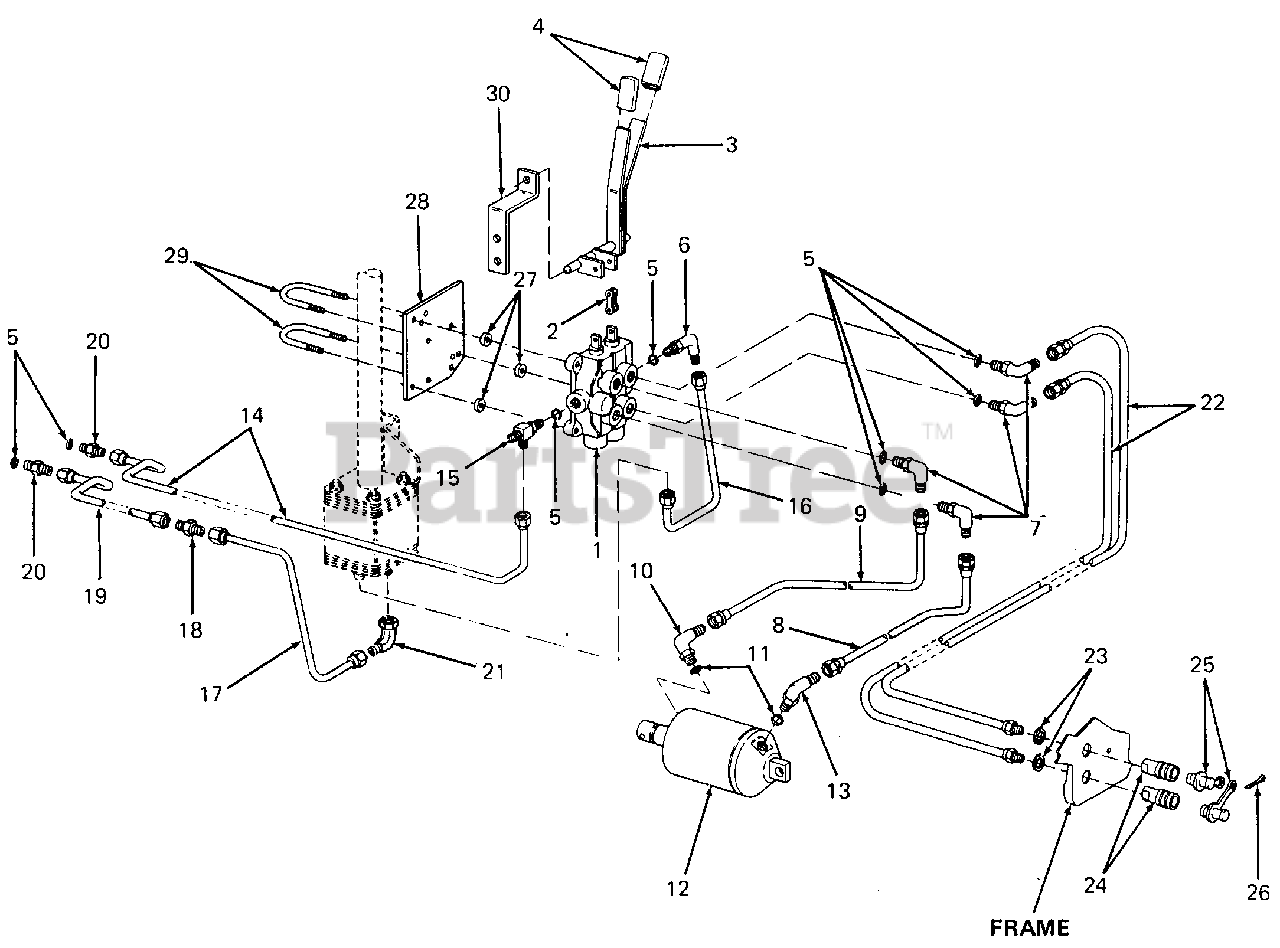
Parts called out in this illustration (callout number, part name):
1	Valve Assy, 2 Spool Control
2	Link, Chain
3	Handle Assy, 2 Spool Valve
6	Elbow, 90 Deg Tube
7	Elbow, Reducer, 3/8 to 1/4
8	Hose, Extending
9	Hose, Retracting
10	Elbow, 90 Deg w/O-Ring
11	O-Ring, 1/4 OD Tube
12	Cylinder, Hydraulic
13	Elbow, 45 Deg w/O-Ring
14	Tube Assy, Return
15	T-Fitting
16	Tube Assy, Valve Pressure
17	Tube Assy, Pump Pressure
18	Union Fitting
19	Tube Assy, Pump Pressure
20	Connector, 37 Deg Tube
21	Fitting, 90 Deg
22	Hose, Pressure Supply
23	Ring, External Retaining
24	Coupling Body, Hydraulic
25	Plug, Protective
26	Pin, Cotter, 3/16 X 3/4 Lg
27	Spacer, .267 X .406 X .375 Lg
28	Plate, Valve Support
30	Support, Valve Handle
